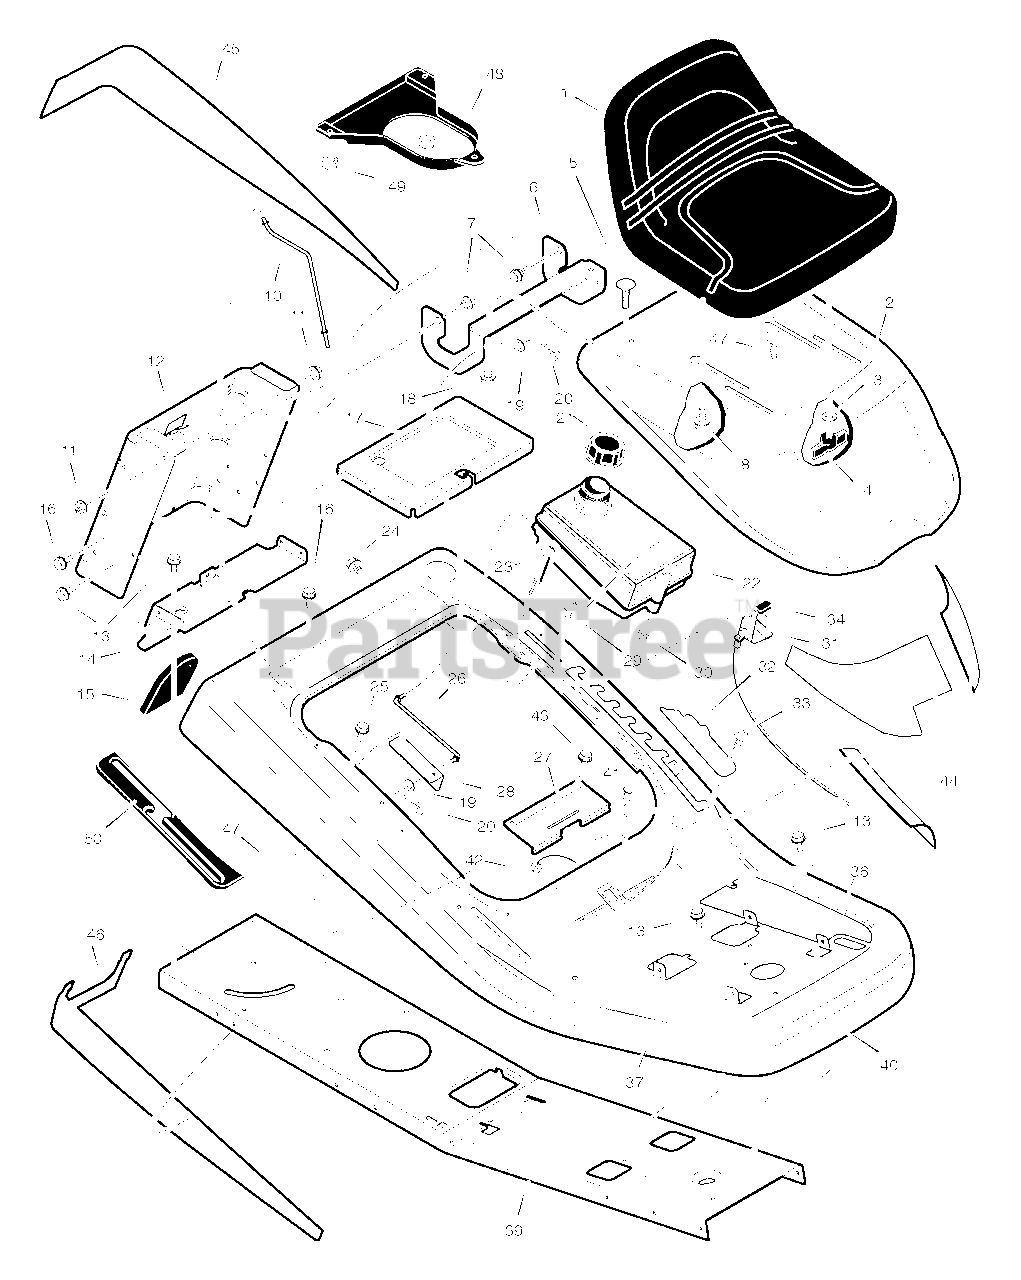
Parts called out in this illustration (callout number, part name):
1	Seat
3	Washer
4	Bolt, Wing
5	Bolt, Carriage
6	Bracket, Hinge
7	Bolt, Shoulder
8	Bolt, Shoulder
10	Rod, Battery
11	Nut, Flange
12	Plate, Rear
14	Plate, Hitch
17	TRAY, Battery
18	Nut, Flange
19	Washer
20	Pin, Hair
21	Cap, Fuel Tank
22	Tank, Fuel
23	Screw
26	Rod, Hood Prop
27	Spring, Seat Deck
28	Bracket, Prop Rod
30	Nut, NY-Lock
31	Control, Throttle
32	Cover, Detent (Black)
33	Bolt, Shoulder
36	Footmat, Left (Black)
37	Footmat, Right (Black)
40	Deck, Seat
41	Bumper
42	Nut
43	Screw
44	Kit, Foil Heat Shield
45	Trim, Left
46	Trim, Right
47	Fastener, Panel
49	Nut, Hex 5/16-18
50	Cover, Long Black
